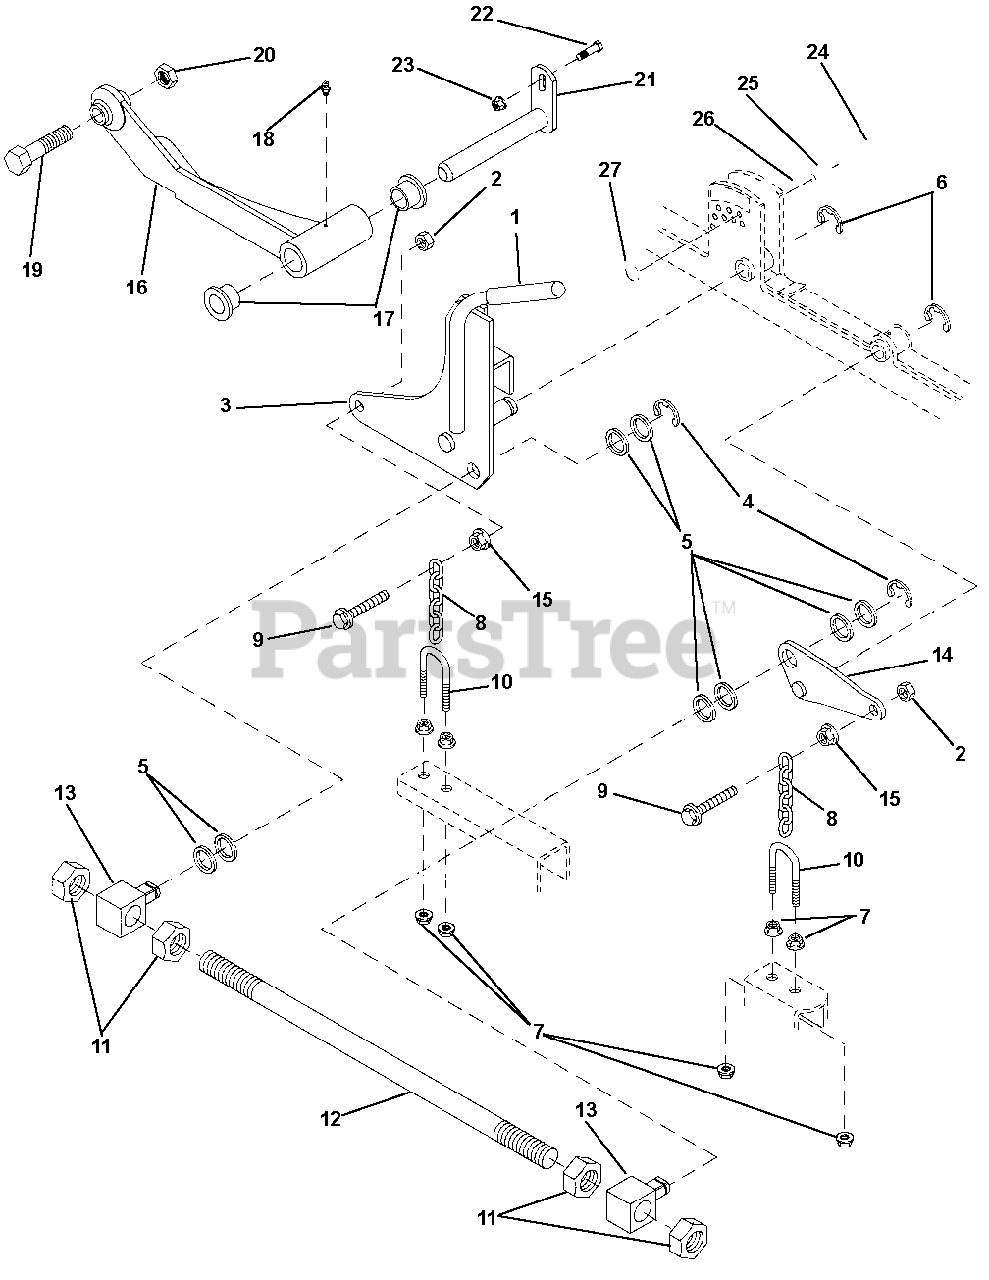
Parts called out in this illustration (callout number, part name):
1	Grip, Control Lever
2	Locknut, M10 x 1.50
3	Weldment, LH Rear Lift Arm
4	Ring, Retaining
5	Washer, JDS24 .891 x 1.375 x .048
6	Ring, Retainer
7	Nut, Flange .375-16
8	Chain, 6 Links
9	Bolt, M10 x 1.5 x 40
11	Nut, Hex .75
12	Rod, Deck Lift Assembly
13	Swivel, Deck Lift
14	Lift Arm Weldment, LH Front
15	Locknut, M10 x 1050
16	Thrust Arm, LH (994100)
17	Bearing, Flanged
18	Fitting, Lubrication
19	Bolt, Hex .75-10 x 3.00
20	Crown Locknut .75-16
21	Pin, Welded
22	Bolt, Round Head Square Neck M8-1.25 x 25
23	Nut, Lock, Nylon M8-1.25
24	Pin, Clevis
25	Bushing, H.O.C. Pin Assembly
26	Pushnut, M12 Bolt Retainer
27	Ring, Locking
